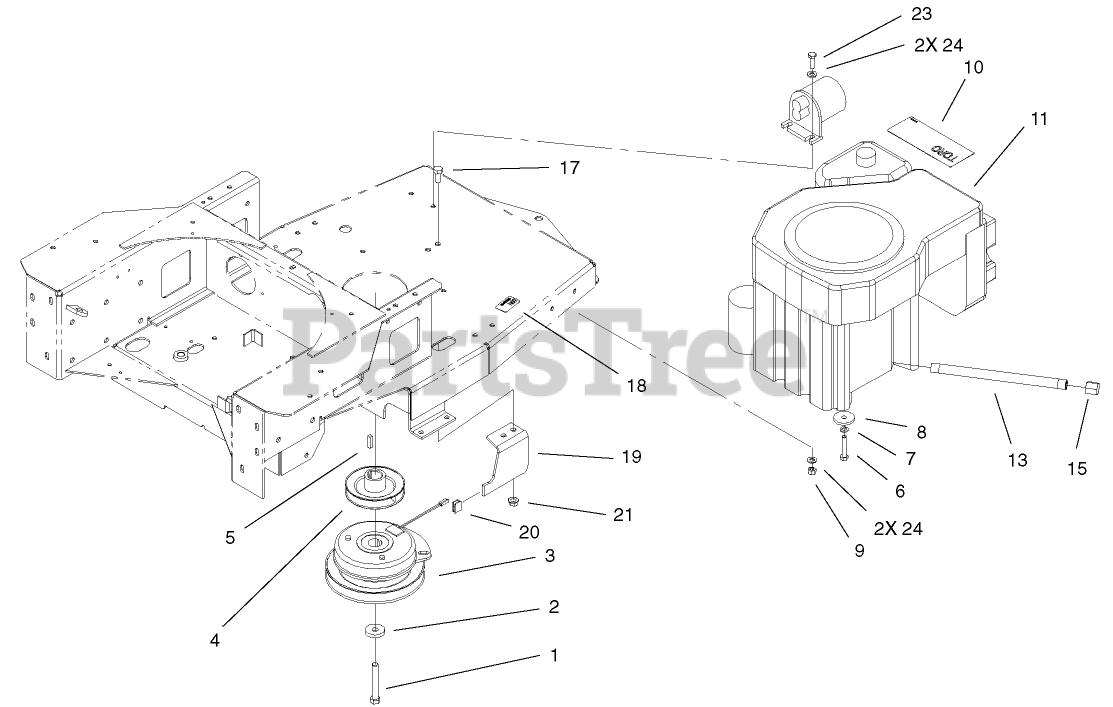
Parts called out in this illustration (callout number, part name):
1	SCREW-HH
2	WASHER
3	CLUTCH
4	PUMP DRIVE PULLEY ASM
6	SCREW-HH
7	WASHER-LOCK
8	SPACER-STEEL
9	NUT-LOCK, NI
13	NIPPLE-PIPE
15	CAP-PIPE
17	SCREW-HH
18	DECAL-SURFACE, HOT
19	STOP-CLUTCH
20	BUMPER
21	NUT-HF
23	SCREW-HH
24	WASHER-PLAIN
